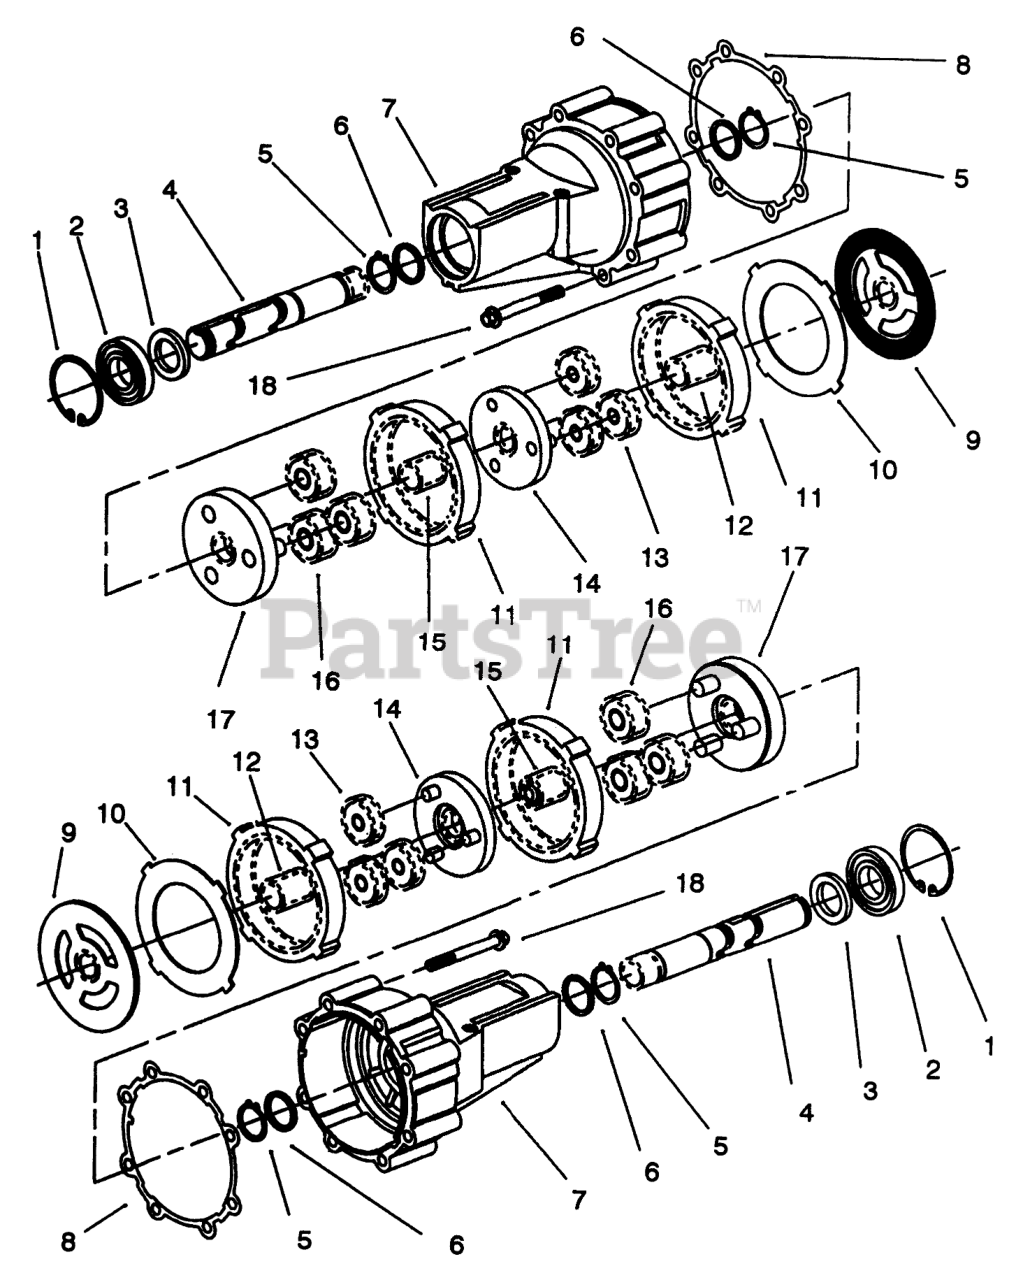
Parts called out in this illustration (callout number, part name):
1	RETAINING RING
2	BALL BEARING
3	RADIAL LIP SEAL
4	AXLE SHAFT
5	RETAINING RING
6	THRUST WASHER
7	AXLE HOUSING
8	AXLE HOUSING GASKET
9	REACTION PLATE
10	BACKUP PLATE
11	57 TOOTH RING GEAR
12	15 TOOTH FIRST GEAR
13	21 TOOTH PLANET. GEAR
14	15 TOOTH PRIMARY CARR.
15	15 TOOTH SECOND GEAR
16	21 TOOTH SECOND GEAR
17	SECONDARY CARRIER
18	5/16 HEX HEAD SCREW
